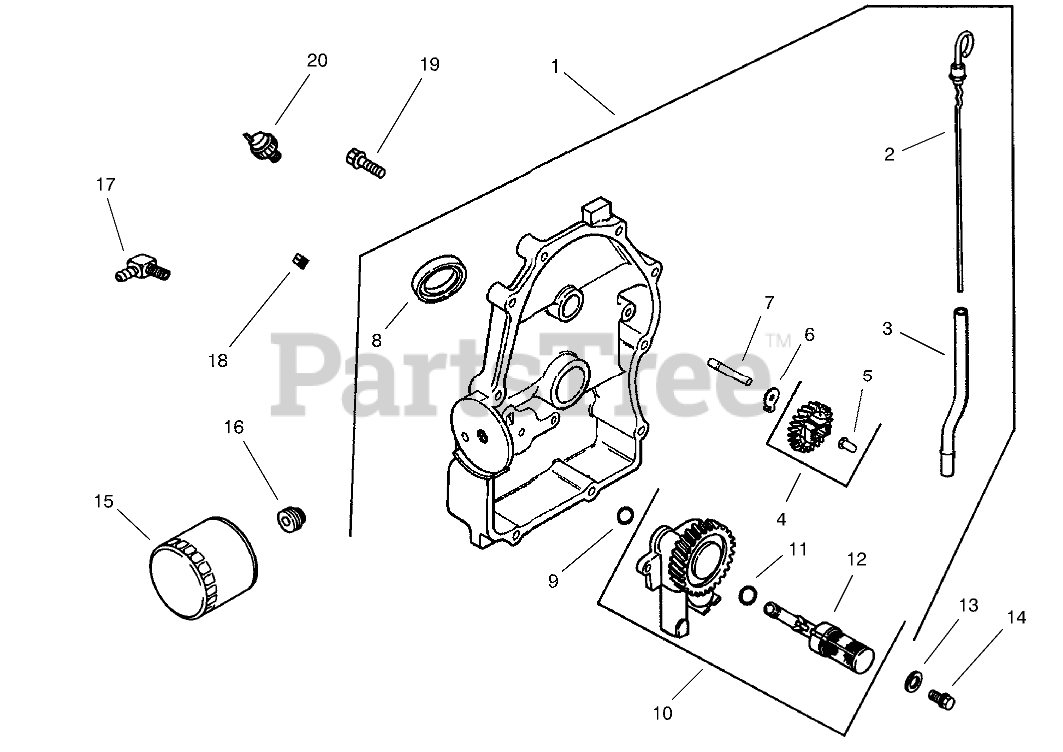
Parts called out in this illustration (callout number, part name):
1	Plate, closure assembly (Includes 2-12)
2	Dipstick
3	Tube-Dipstick
4	Kit, governor gear (Includes 5)
5	Pin-Governor
6	Tab-Locking
7	Shaft-Gear, Governor
8	Seal-Oil
9	O Ring
10	Oil pump assembly (Includes 11, 12)
11	O-Ring
12	Pick Up-Oil
13	Washer
14	Screw
15	Filter-Oil
16	Nipple-Filter, Oil
17	Connector
18	Plug
19	Screw
20	Switch, pressure
